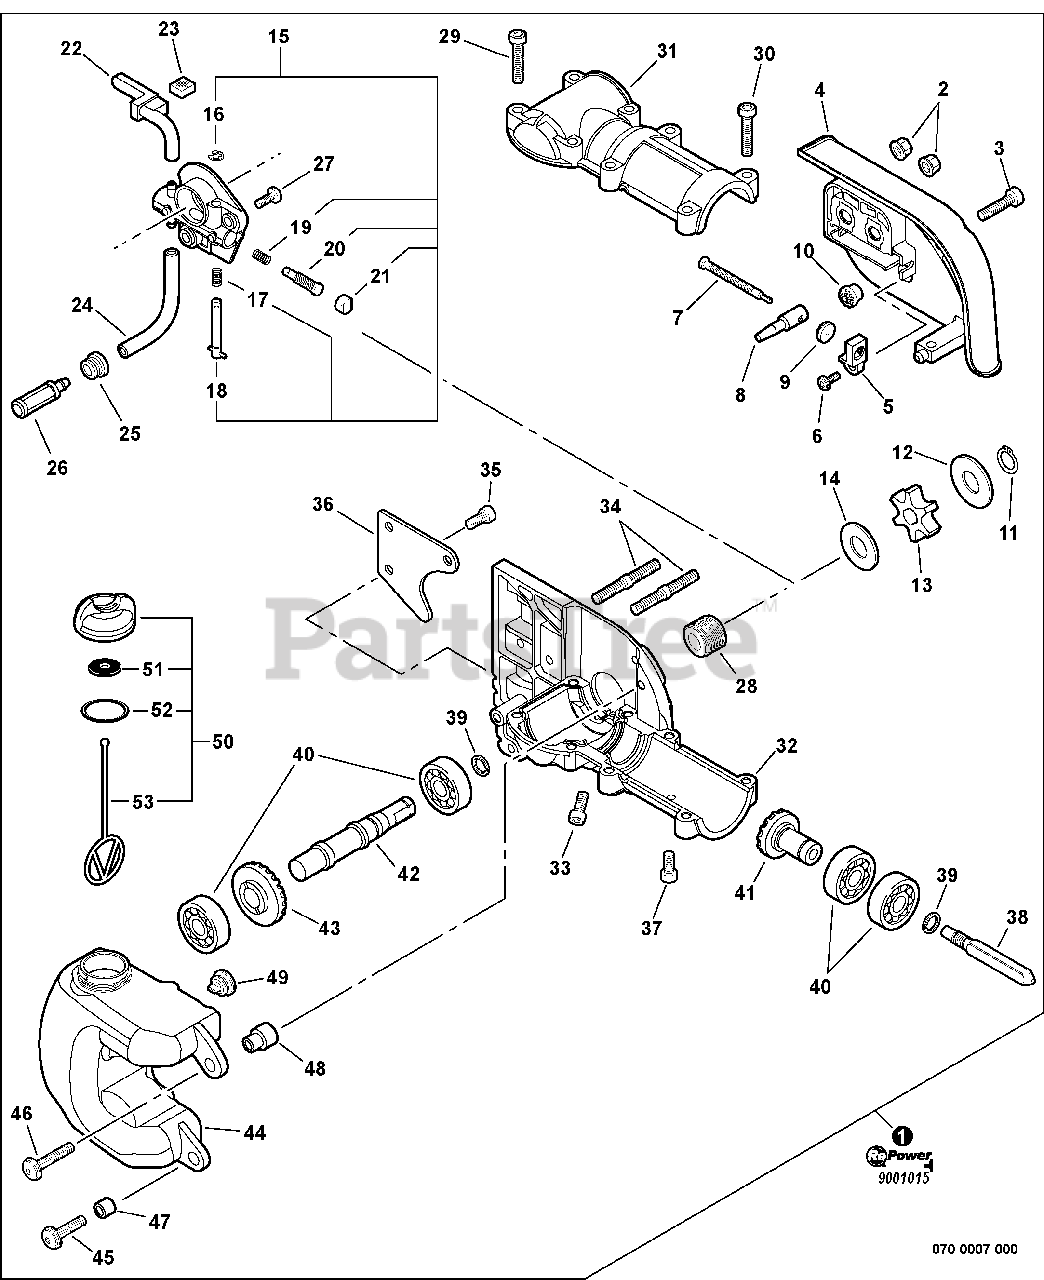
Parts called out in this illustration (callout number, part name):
1	CUTTING HEAD ASSY
2	NUT - 6 -- FLANGE
3	SCREW - 5X20
4	GUARD, SPROCKET
5	BRACKET, TENSIONER
6	SCREW - 4X8
7	SCREW, TENSIONER
8	TENSIONER, CHAIN
9	GEAR - BEVEL
10	GEAR - BEVEL
11	RING, RETAINING
12	WASHER - 10
13	SPROCKET, DRIVE
15	AUTO-OILER ASSY
16	RING, RETAINING
18	NEEDLE, ADJUST
20	PLUNGER
21	CAP, OIL PUMP
22	PIPE, OIL OUTLET
23	PAD, FOAM
24	PIPE - 3X6X75 -- BLACK
25	GROMMET
26	FILTER, OIL
27	SCREW - 5X10
28	GEAR - WORM
29	SCREW - 5X25
30	SCREW - 5X25
31	CASE, GEAR - UPPER
32	CASE, GEAR - LOWER
33	SCREW - 5X10
34	STUD, GUIDE BAR
35	SCREW - 5X10
37	SCREW - 5X10
38	CONNECTOR, SHAFT
39	RING, RETAINING - 12
40	BEARING, BALL - 6001
41	GEAR - BEVEL
42	GEAR - SHAFT
43	GEAR - BEVEL
44	TANK, OIL
45	SCREW - 5X20
46	SCREW - 5X25
50	CAP ASSY - ORANGE
51	WASHER - RUBBER
52	O-RING - 18
53	CONNECTOR, CAP
